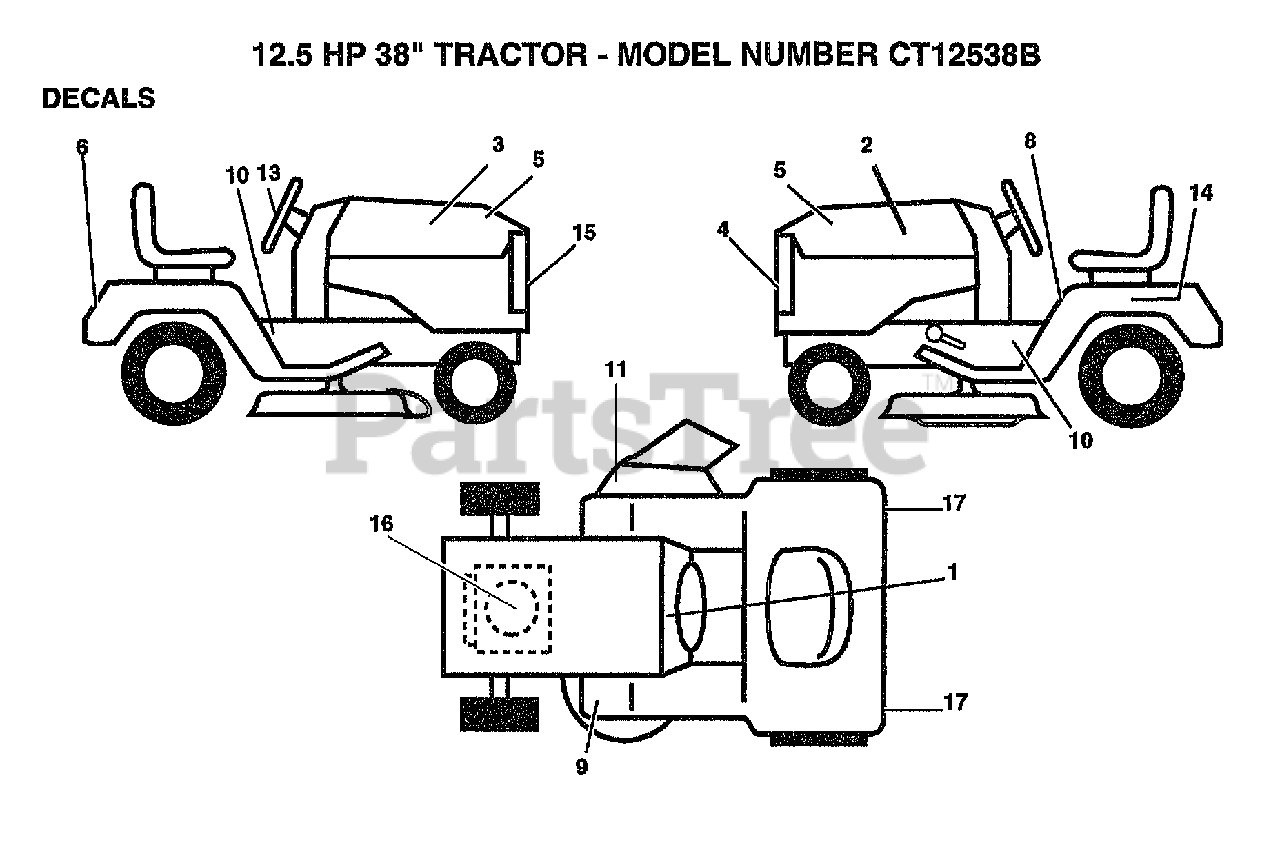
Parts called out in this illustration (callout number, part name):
4	GRILL DECAL
5	"DECAL, HP HOOD"
6	FENDER DECAL
8	DECAL CAUTION
9	DECAL T
11	"DECAL, WARNING"
13	"DECAL,STR WHL"
14	DECAL
17	REFLECTOR-TAIL YT
